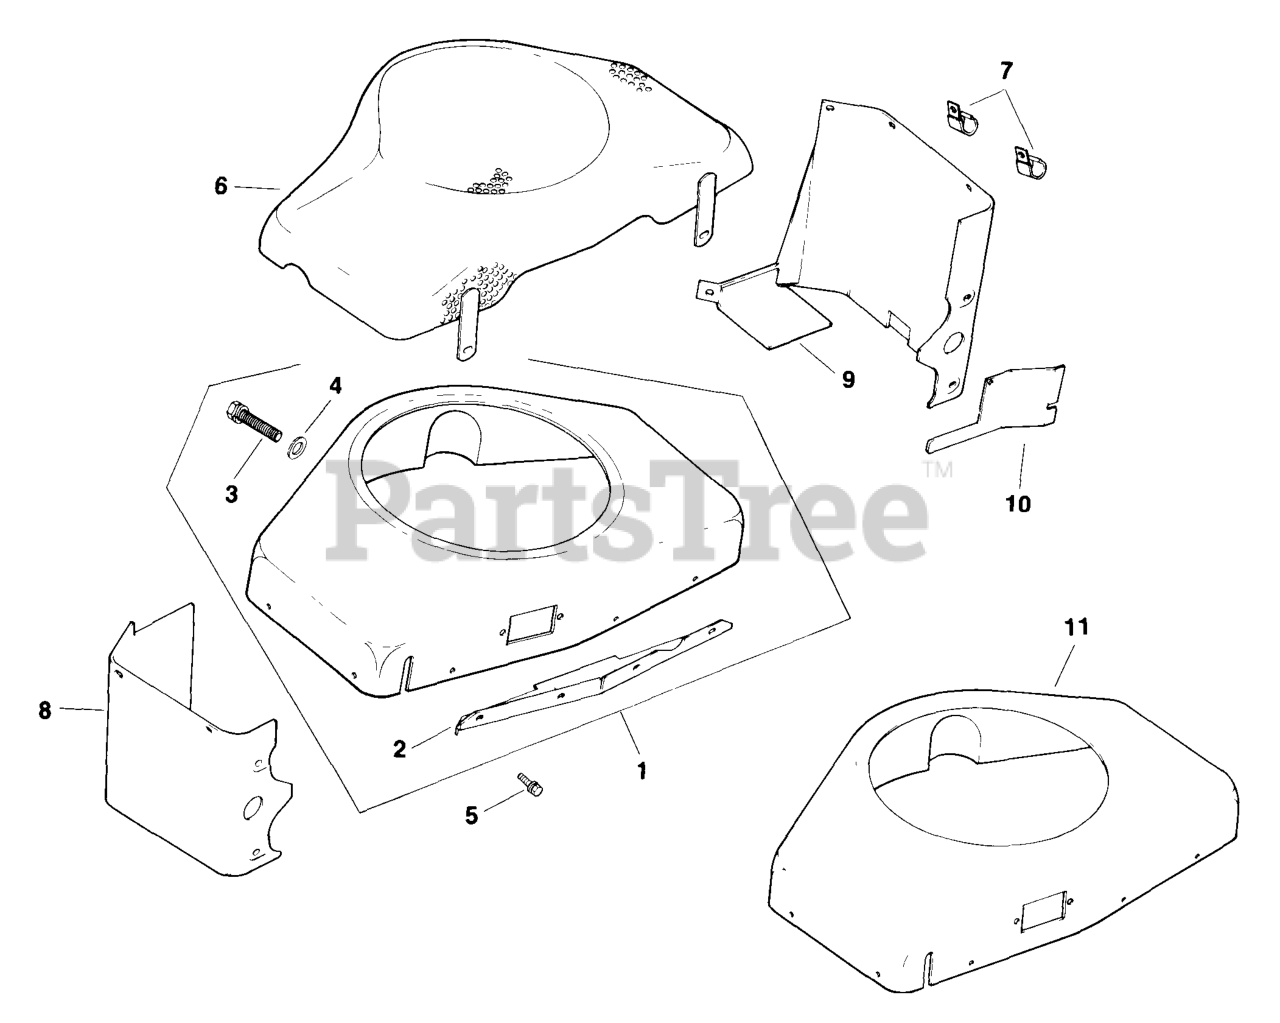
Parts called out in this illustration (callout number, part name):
1	Kit, Blower Housing
2	Support, Upper Housing
3	Screw, Hex. Wash. Hd. 1/4-20x5/8"
4	Washer, Flat 1/32"
6	Screen, Grass
8	Baffle, #1 Cylinder Head
9	Baffle, #2 Cylinder Head
10	Baffle, Fuel Pump
